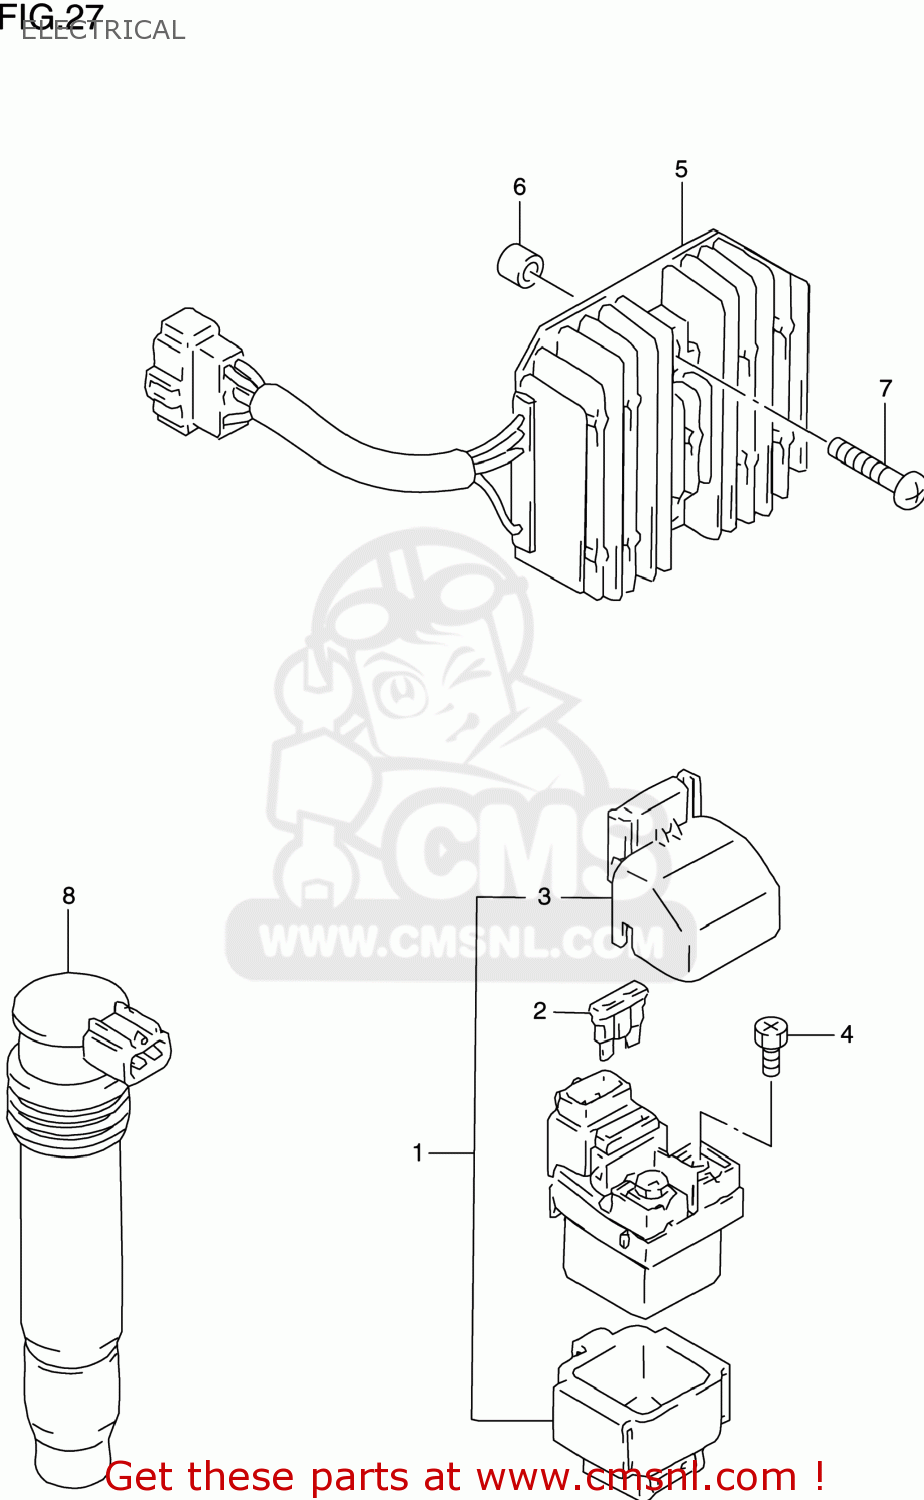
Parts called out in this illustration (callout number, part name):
1	RELAY ASSY,STARTING MOTOR
2	FUSE(30A)
3	COVER,STARTER RELAY
4	SCREW(6X8)
5	RECTIFIER ASSEMBLY
6	SPACER(6.5X10X7)
7	SCREW
8	COIL ASSY,IGNITION
